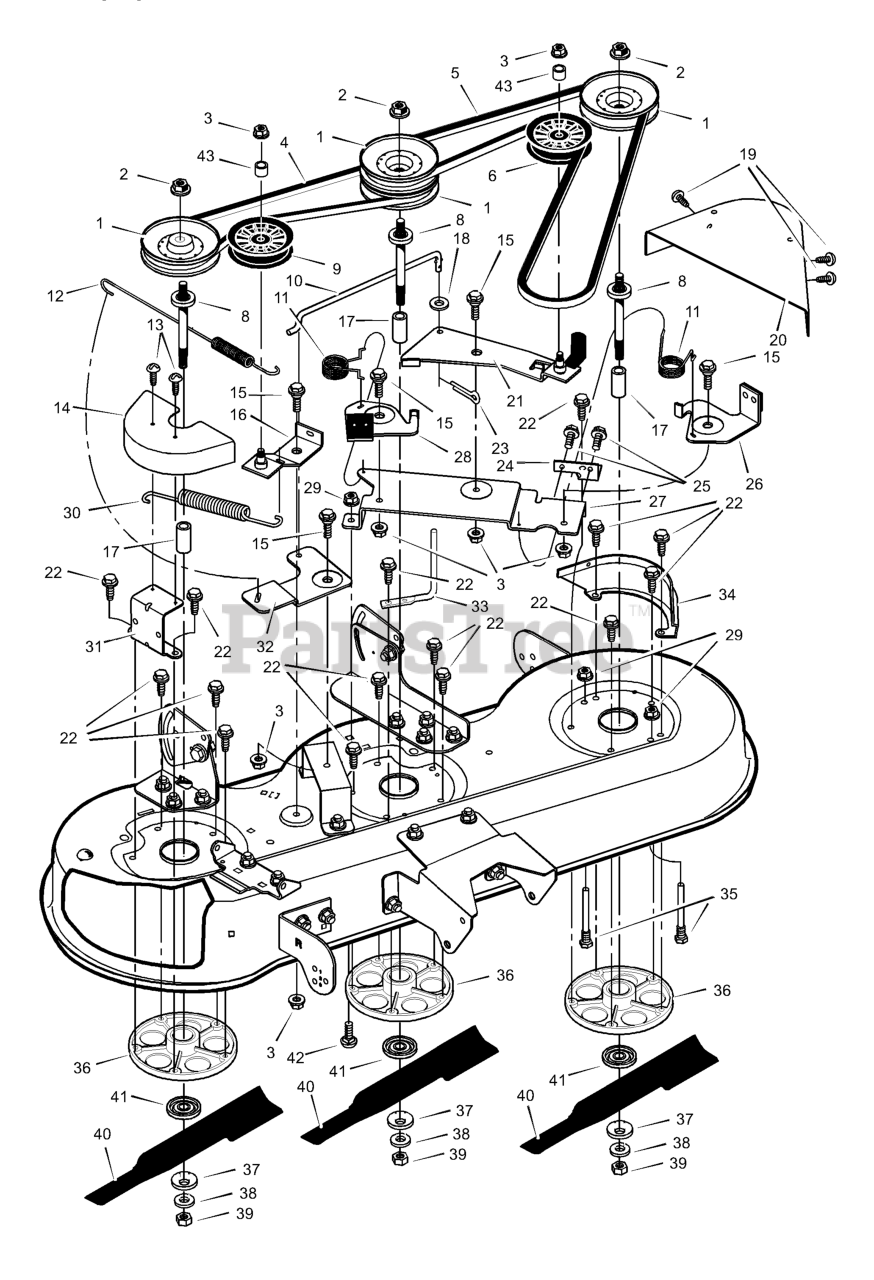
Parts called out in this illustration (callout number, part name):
1	Pulley
3	Nut
4	Belt, Secondary
5	Belt, Primary
6	Pulley, Idler
8	Jackshaft
9	Pulley, Idler
10	Link, Bell Crank
13	Screw
14	Cover, Right Pulley
15	Bolt, Shoulder
16	Arm Assembly, Idler
18	Washer
20	Cover, Left Pulley
21	Arm Assembly, Idler
22	Bolt
23	Pin, Cotter
24	Bracket, Brake Plate
26	Brake Assembly, Left
27	Plate, Brake Arm
28	Brake Assembly, Center
29	Nut, Flange
31	Bracket, Cover
32	Bell Crank
33	Guide, Belt
34	Bracket, Pulley Cover
35	Guide, Belt
36	Housing, Jackshaft
39	Nut, Blade
41	Adapter, Blade
42	Bolt, Carriage
